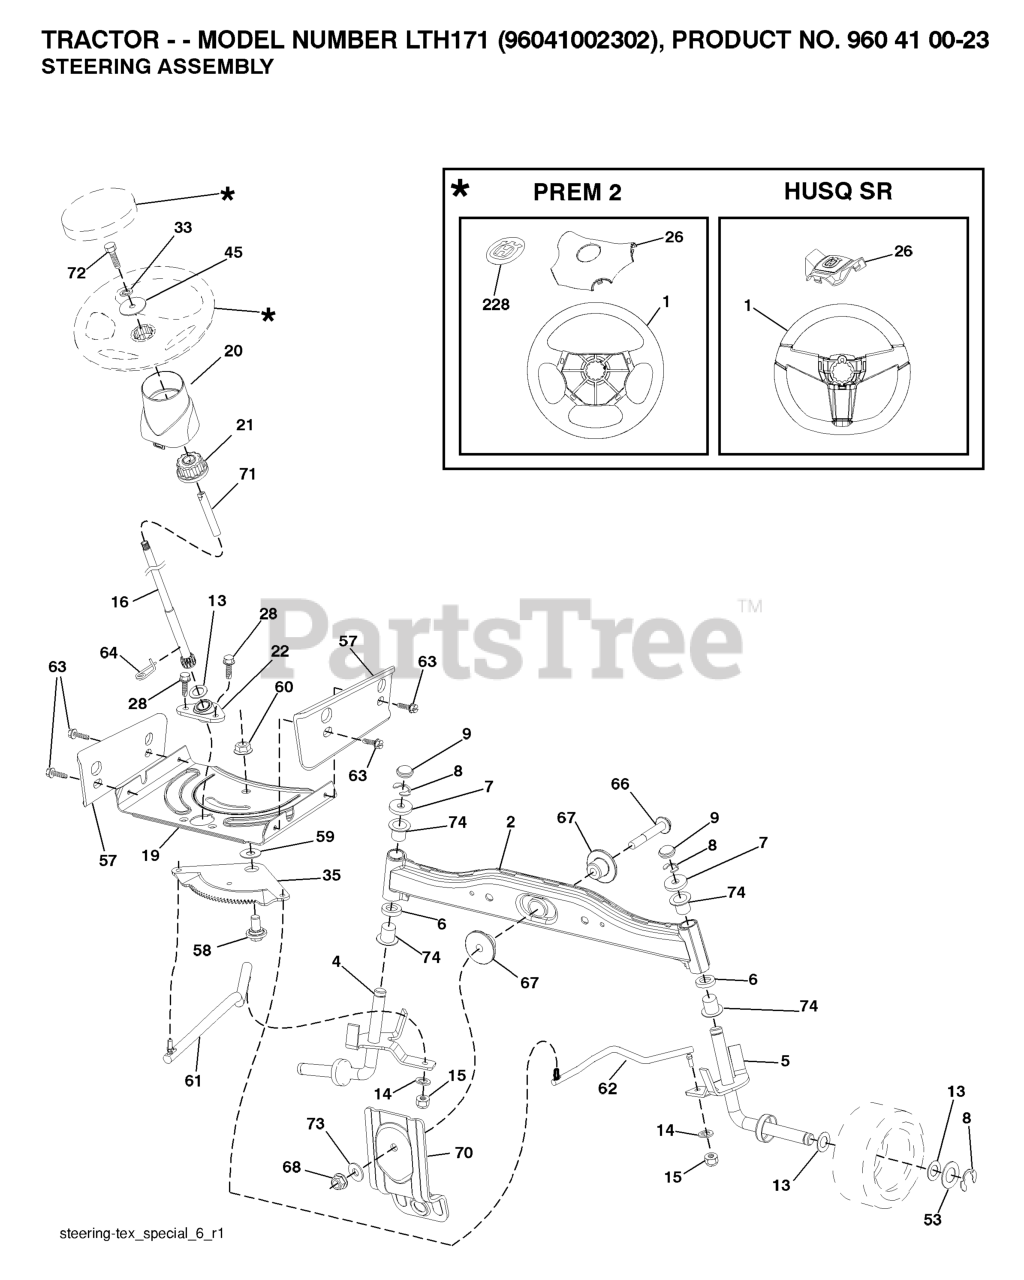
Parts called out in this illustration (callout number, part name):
1	RP WHEEL.STEER.HUSQ.PREM.OVMLD
2	AXLE.HALF.ASM.WELDED
4	SPINDLE.WELDED.LH.15"TEX
5	SPINDLE.WELDED.RH.15"T
6	THRUST WASHER
9	CAP.SPINDLE.BLACK
14	WASHER, LOCK 3/8
15	NUT CROWNLOCK 3/8-24
16	SHAFT STEERING
19	PLATE.STEER.DDL.NLT/NG
20	BOOT, STEERING
21	ADAPTER, WHEEL STNG..
22	BUSHING.ASM.STEERING.A
26	RP INSERT.CAP.WHL.STRG.HUSQ.
28	SCREW, 3/8-16X3/4
33	WASHER.LOCK.HVY.HLCL.SPR.5/16
35	GEAR.SECTOR.PLATE.DDL.
45	WASHER.11/32
53	WASHER.HARDENED
57	BRACKET.UPSTOP.TEX
58	BOLT.SHOULDER.SECTOR.P
59	WASHER.THURST.SECTOR.S
60	NUT FLANGE LOCK 5/8-11
61	DRAGLINK.LH.BALLSTUD.D
62	DRAGLINK.RH.BALLSTUD.D
63	SCREW
64	RETAINER.CLIP.SPRING.S
66	BOLT HEX FGHD 7/16-14 X 3 SERR
67	BUSHING.PM.FRONT AXLE
68	NUT.LOCK.FLANGE.7/16
70	BRKT.DECK.SUSPENSION.F
71	SHAFT EXTENSION STEERING
72	BOLT YT
73	WASHER.1.5X.505X.118
74	BRNG T
228	DECAL.WHEEL.STRG.LGN.H
